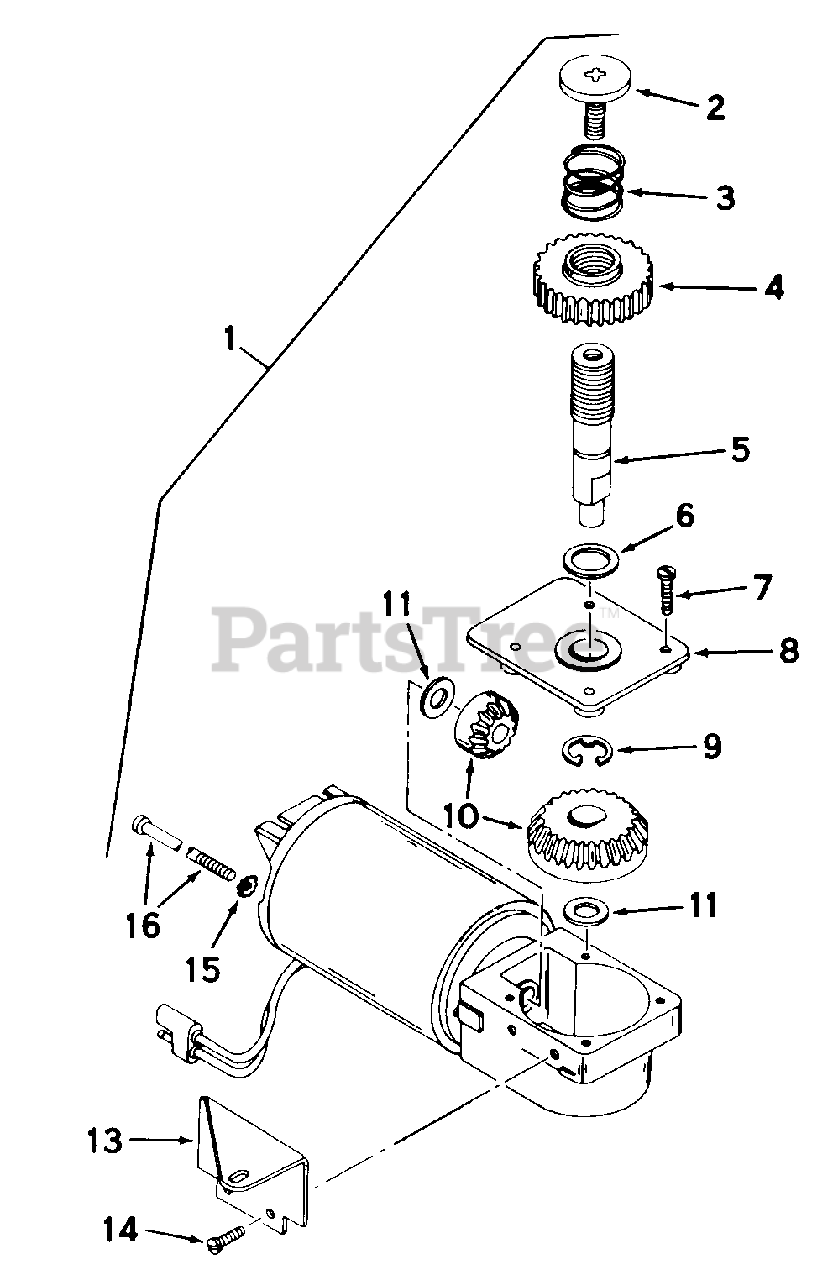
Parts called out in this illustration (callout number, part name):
1	"Motor, Electric starter
2	Screw, Drive (Left hand thread)
3	Spring, Return
4	Gear, Starting
5	Shaft, Center
6	Washer, Thrust
7	Screw, 10-32 x 5/8 Low Hex washer hd.
8	Cover Assy
9	Ring, Retaining
10	Gear Set
11	Washer, Shim
13	Bracket, Front mounting
14	Screw
15	Lockwasher, No. 8 E. T.
16	Screw, 8-32 x 3-3/8 rd. hd
